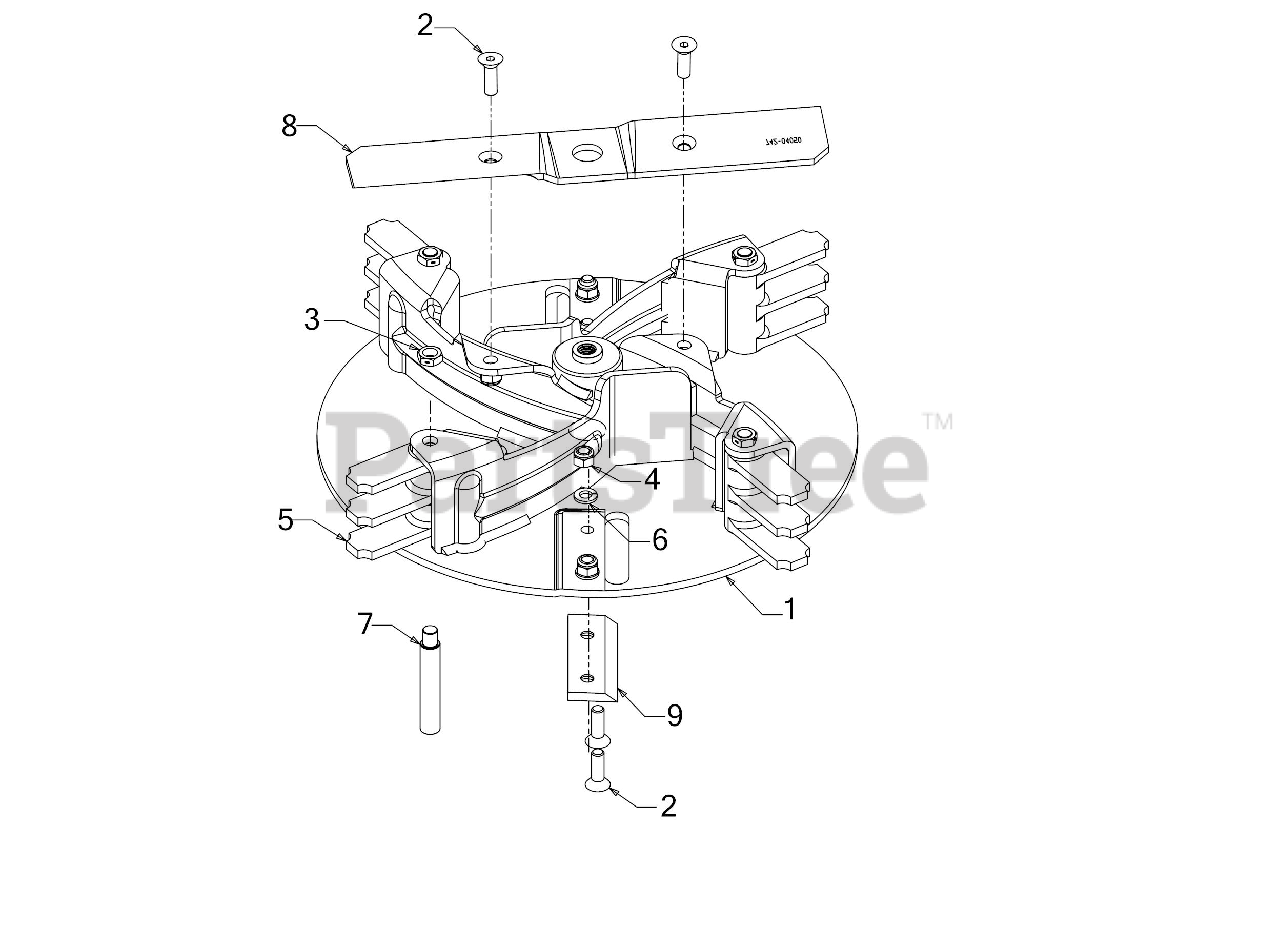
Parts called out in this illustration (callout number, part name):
1	IMPELLER
2	SCREW 5/16-24 x 1
3	JAM LOCK NUT
4	HEX NUT
5	FLAIL BLADE
6	LOCK WASHER 5/16
7	SHOULDER PIN
8	IMPELLER BLADE
9	CHIPPER BLADE
